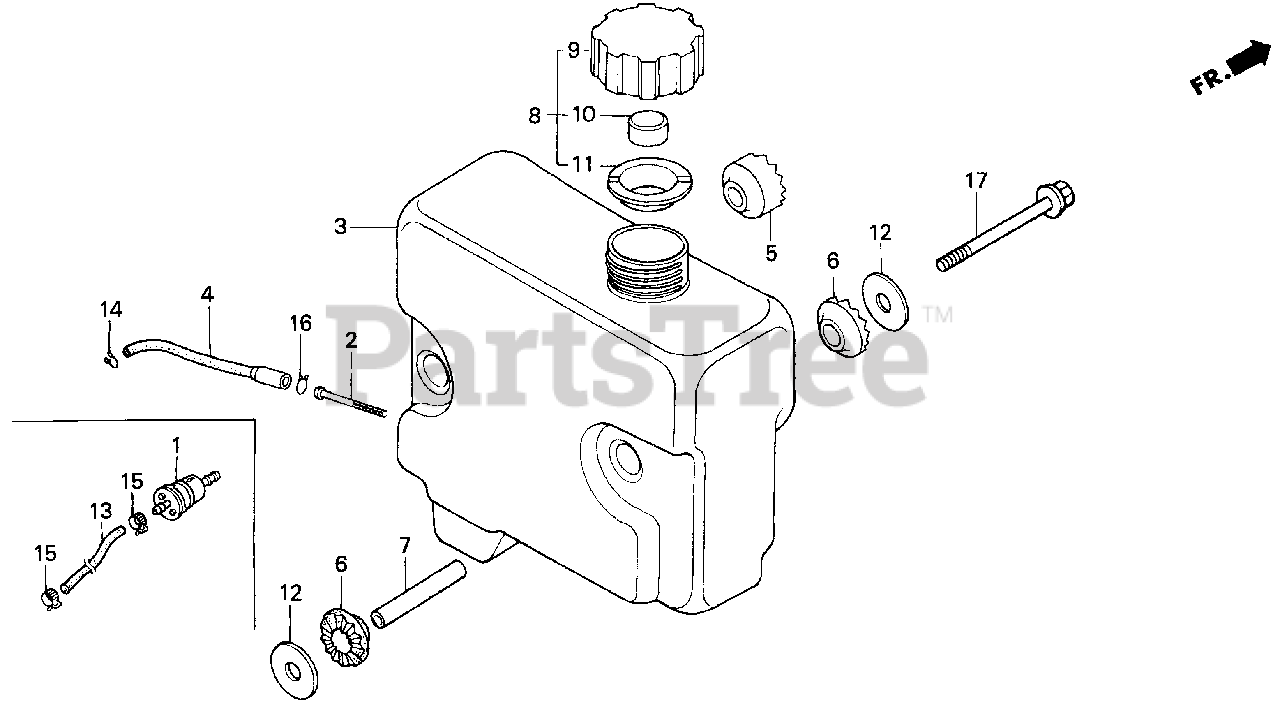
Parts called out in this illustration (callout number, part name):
2	FILTER, FUEL
3	TANK, FUEL
4	TUBE, FUEL
5	RUBBER B, TANK MOUNTING
6	RUBBER B, TANK MOUNTING
7	COLLAR, TANK SETTING
8	CAP ASSY., FUEL TANK
9	BODY, FUEL CAP
10	SPONGE, FUEL CAP BREATHER
11	GASKET, FUEL CAP
12	WASHER, TANK MOUNTING
14	CLIP, TUBE (B8)
16	CLIP, TUBE (C11)
17	BOLT, FLANGE (8X90)
